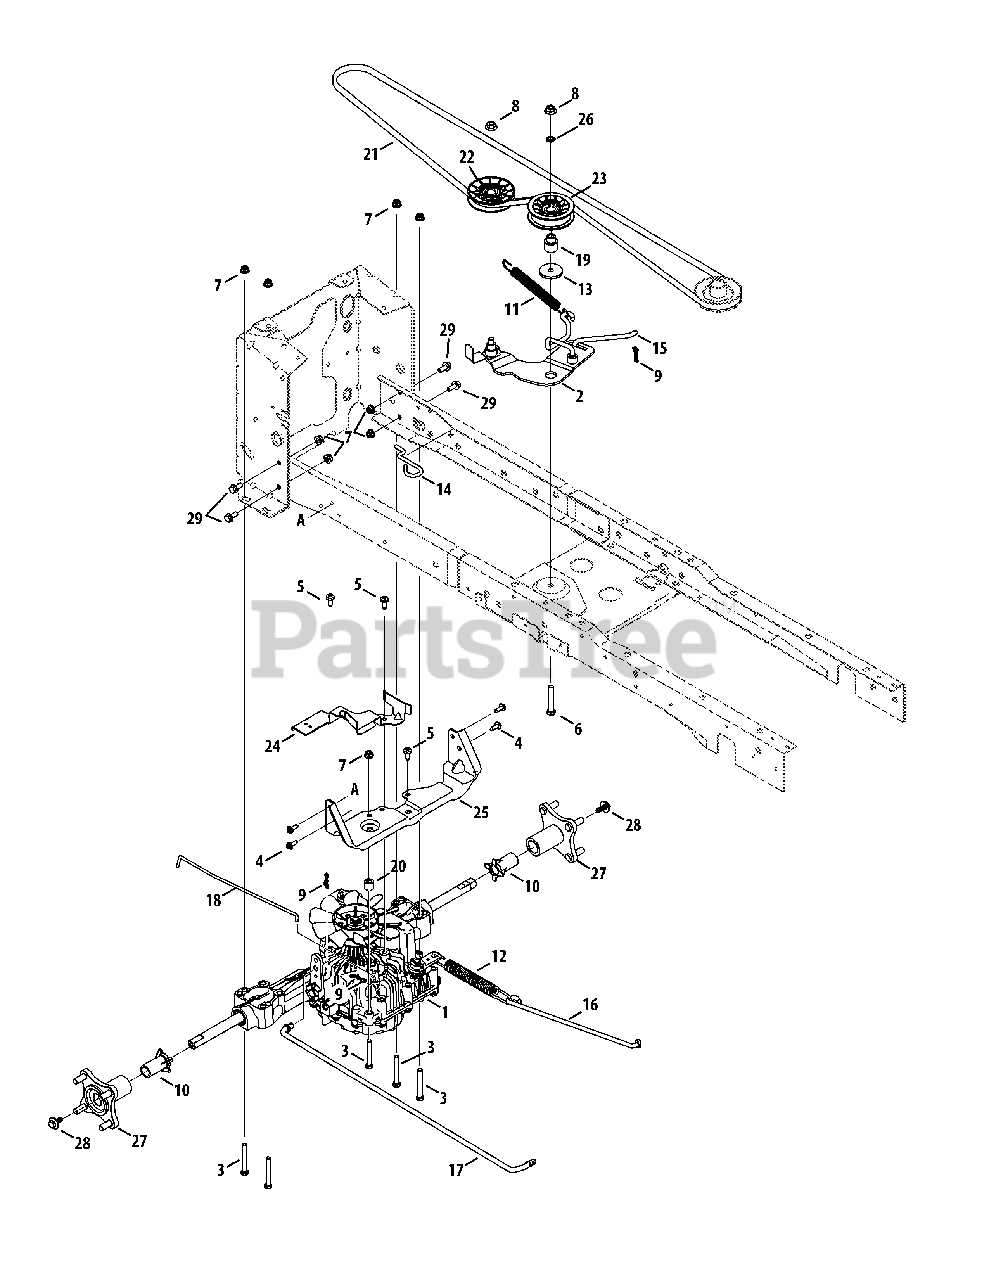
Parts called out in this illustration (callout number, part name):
1	Transmission, Tuff Torq K46
2	Idler bracket Assembly
3	Hex Screw, 5/16-18, 2.50, Gr5, Std
4	Screw, M6-1 x .625
5	Screw, Self-tapping, 5/16-18, 0.750
6	Hex Screw, 3/8-16, 2.25, Gr5
7	Nut, Flange Lock, 5/16-18, Nylon
8	Flange Lock Nut, 3/8-16
9	Pin, Cotter, Bow-Tie 72
10	Sleeve, .765 Id x 2.11
11	Spring, Extension, .700 Dia x 8.41
12	Spring, Extension, .90 Dia x 8.14
13	Shoulder Spacer, .884 x .190
14	Deck Spring Rod
15	Idler Link
16	Rod, Brake, Tuff Torq
17	Rod, Control, Tuff Torq
18	Rod, Transmission, Bypass
19	Shoulder Spacer
20	Spacer, .34 x .75 x .63
21	Belt, V-Type
22	Idler Pulley, 3.56 OD
23	Idler Pulley, 3.00 OD
24	Belt Keeper Bracket
25	Transmission Bracket
26	Speed Nut
27	Hub Assembly, Wheel
28	Screw, 5/16-24 x .850
29	Flange Lock Screw, 5/16 x 3/4
